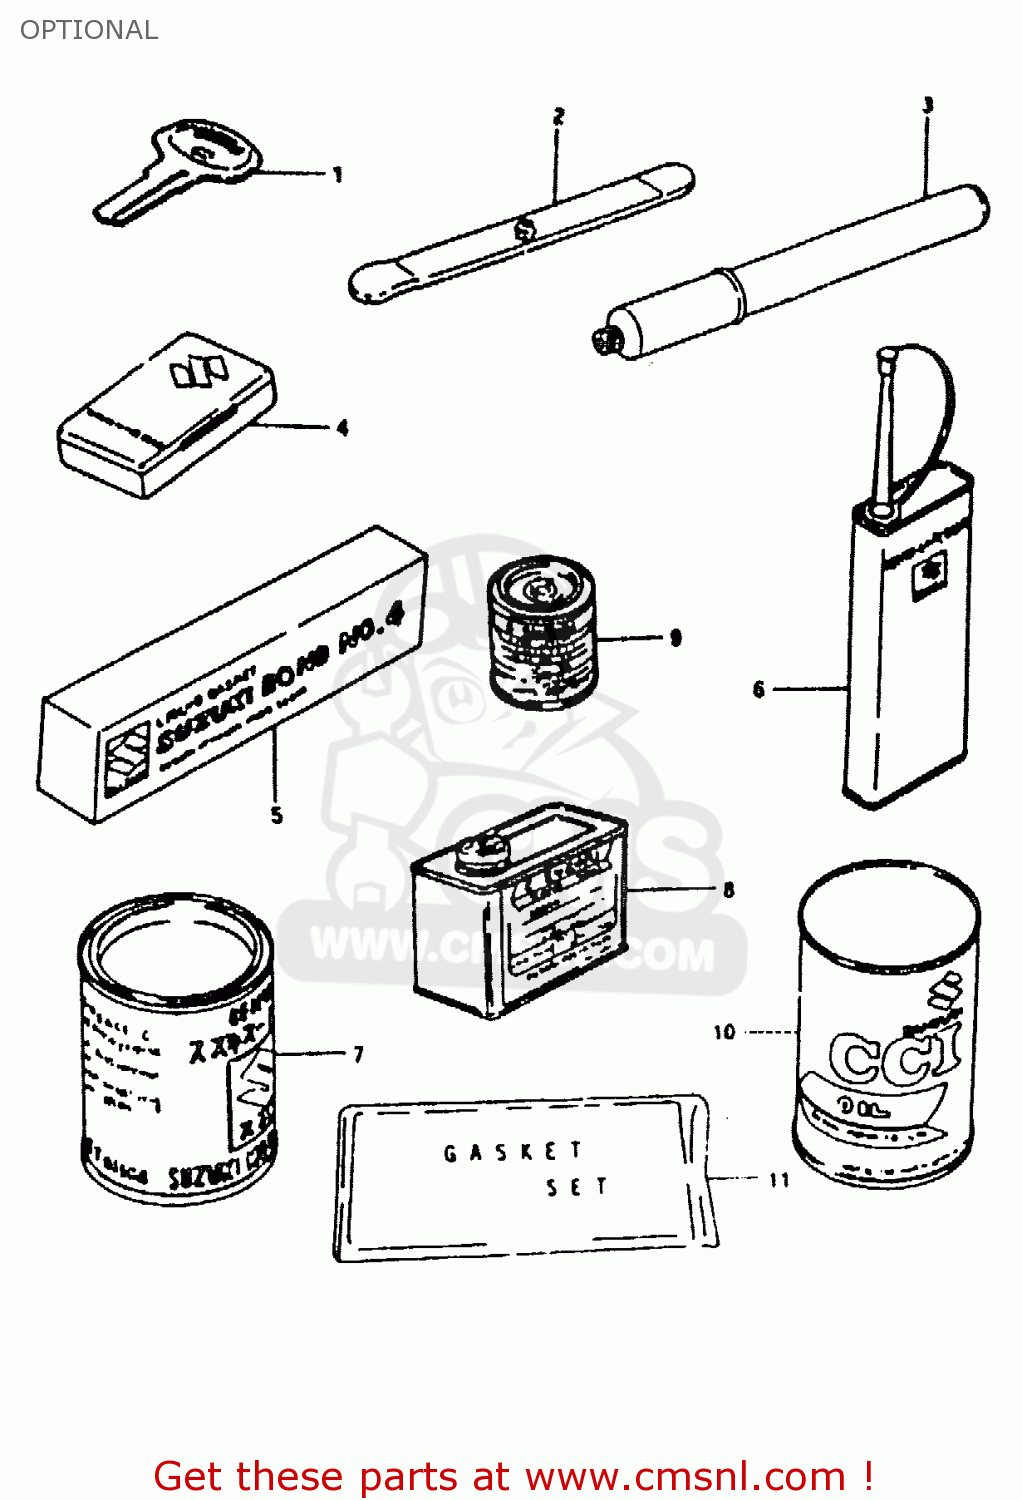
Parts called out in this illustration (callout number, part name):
1	KEY,BLANK
2	LEVER,TIRE
3	INFLATOR, AIR
4	TUBE REPARING TOOL
5	BOND 1104
6	THREAD LOCK NO.1401 CLEAR 200G
7	GREASE(C)EP2 LITHIUM 150G
8	PAINT (BLACK)
9	PAINT,BLACK
10	CCI OIL
11	GASKET SET (MCA)
